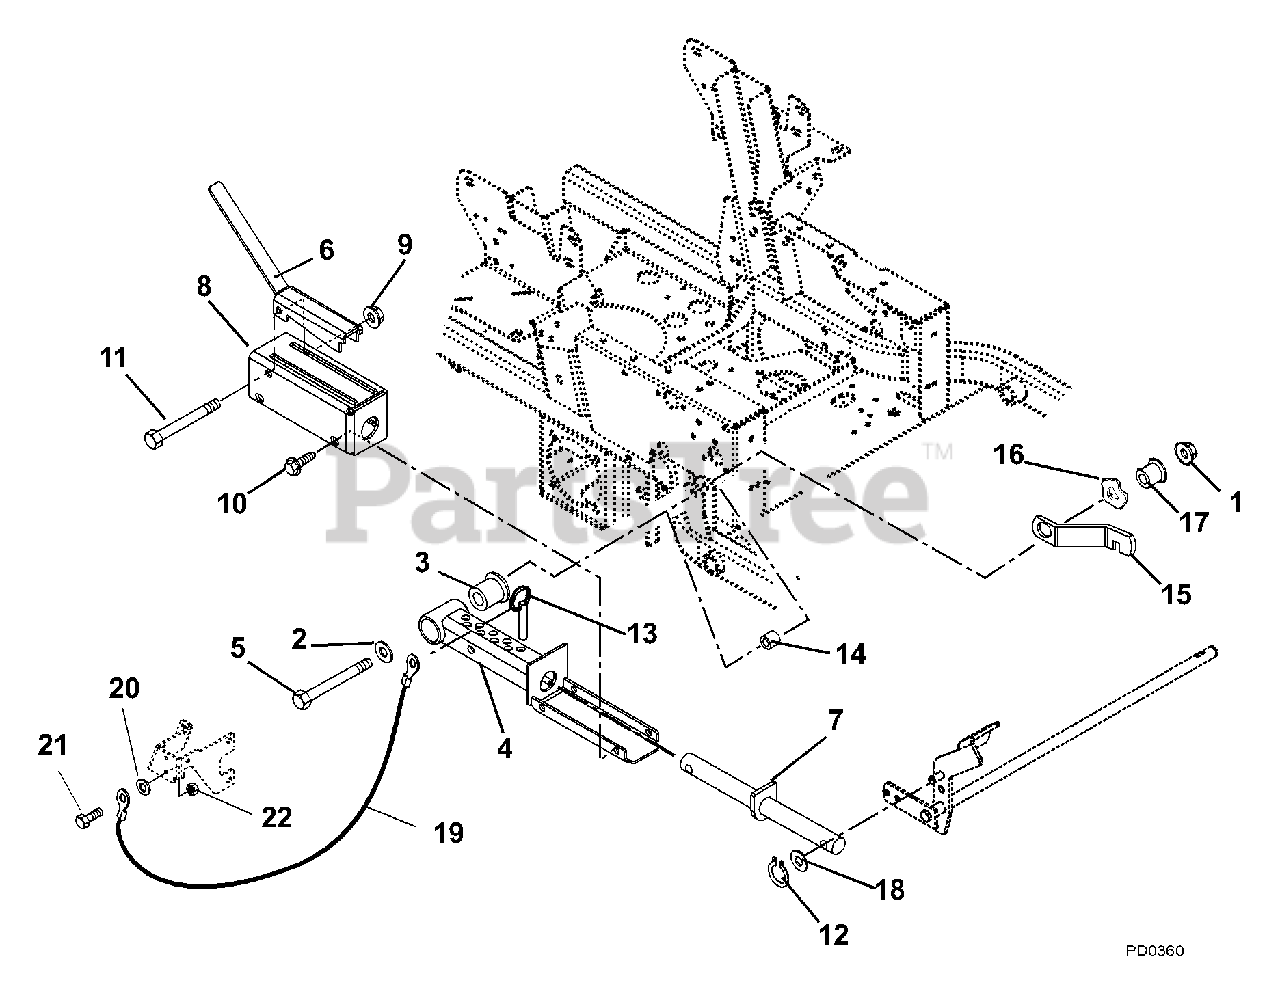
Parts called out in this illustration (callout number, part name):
1	Nut, Locking Top Flange .50-13
2	Washer, Flat Steel .531 x 1.25 x .10
3	Bearing, Pedestal
4	Weldment, Mechanical Lift
5	Bolt-Hex .50-13 x 5.00 Grade 5
6	Lock-Up, Mechanical Lift
7	Weldment, Mechanical Lift Shaft
8	Weldment, Mechanical Lift Cover
9	Nut, Locking Top Flange .38-16
10	Screw, Tapping .38-16 x .50 Hex Washer Head
11	Bolt, Hex .38-16 x 3.25 Grade 5
12	Ring, Retaining External .625 x .05
13	Pin, Spring Ball .375 O.D. x 1.50
14	Spacer .516 ID x 1.00 OD x .875
16	Washer-Wave .076 x 1.120 x .080
17	Bushing-Flange .515 x .750 x .275 x 1.120
18	Washer, Flat Steel .656 x 1.31 x .095
19	Cable, Hood
20	Washer, Flat Steel .265 x .50 x .087
21	Bolt-Hex .25-20 x .75 Grade 5
22	Nut, Locking Top Flange .25-20
